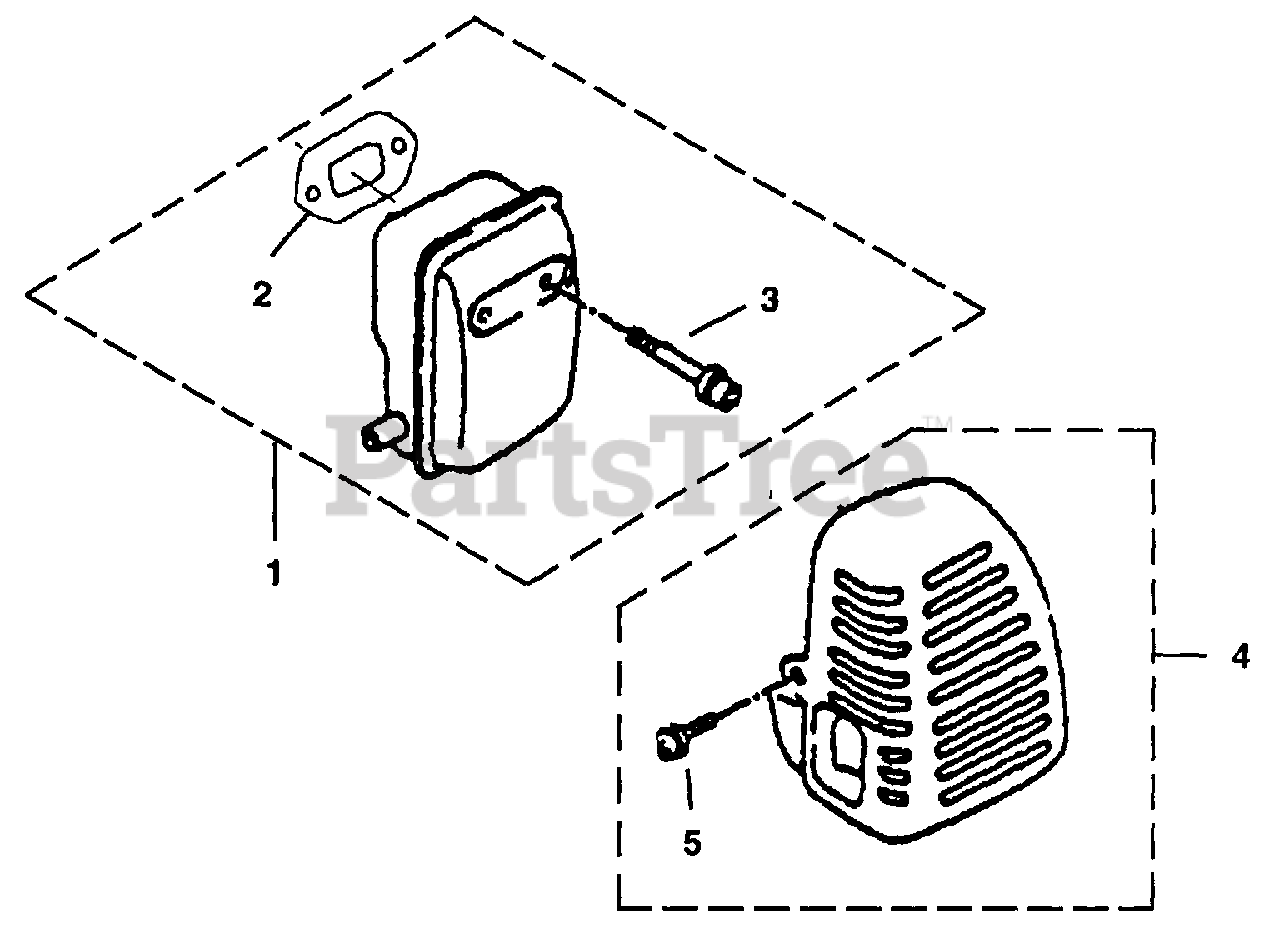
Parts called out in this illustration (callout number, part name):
1	MUFFLER ASSEMBLY
2	GASKET-Muffler
3	SCREW-Socket Hd. (M5 x 55)
4	MUFFLER COVER
5	SCREW ASSEMBLY (M5 x 14)
